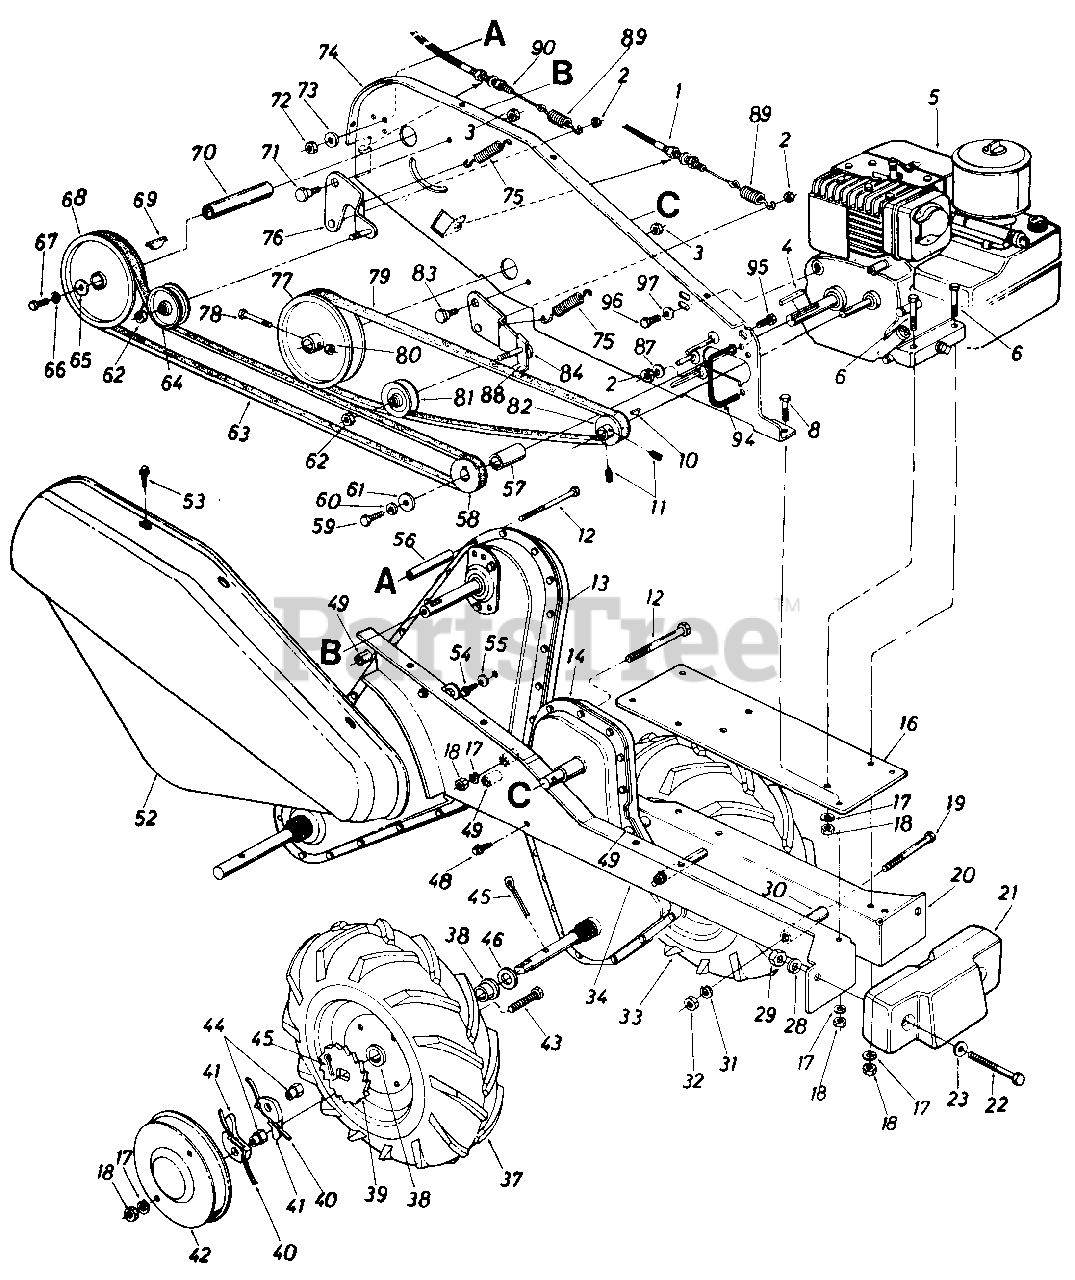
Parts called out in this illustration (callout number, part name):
1	Clutch Control Cable
2	Hex Cent. L-Nut 1/4-20 Thd.
3	Hex Cent. L-Nut 3/8-16 Thd.*
4	Sq. Key 3/16" Dia. x .75
5	Engine
6	Hex Bolt 5/16-18 x 1.50" Lg.*
8	Hex Bolt 5/16-18 x .75" Lg.*
10	Hi-Pro Key #5 Woodruff
11	Set Scr. 1/4-28 x .25" Lg.
12	Hex Bolt 5/16-18 x 3.0" Lg.*
18	Hex Nut 5/16-18 Thd.*
19	Hex Bolt 3/8-24 x 3.0" Lg.*
22	Hex Bolt 1/2-13 x 4.0" Lg.
23	Fl-Wash. 1/2" I.D. x 1.0" O.D.
28	L-Wash. 1/2" I.D.*
29	Hex Nut 1/2-13 Thd.*
30	Spacer 3/8" I.D. x 5/8" O.D. x 2.18" Lg.
31	L-Wash. 3/8" I.D.*
32	Hex Nut 3/8-24 Thd.*
33	Comp. Wheel Ass'y.-L.H.
38	Flange Brg. 7/8" I.D. x 1.12" Lg.
39	Ratchet Wheel
40	Nylon Spring
41	Pawl.44" I.D.
42	Wheel Cover
43	Hex Bolt 5/16-18 x 1.25" Lg.*
44	Special Hex-Nut 5/16-24 Thd.
45	Cotter Pin 1/8" Dia. x 1.25"*
46	Fl-Wash. 7/8" I.D. x 1-3/8" O.D. x .06
48	Hex Wash. Self-Tap Scr. 5/16-24 x .50" Lg.
49	Spacer 5/16" I.D. x .96" Lg.
52	Belt Cover
53	Hex Wash. S-Tap Scr. 1/4-20 0 x.50" Lg.
54	Hex Wash. S-Tap Scr. 1/4-20 0 x 3/8" Lg.
55	Bell-Wash. 1/4" I.D.
56	Spacer 3/8" I.D. x 2.0" Lg.
57	Spacer 3/4" I.D. x 1.56" Lg.
58	1/2" "V"-4L Pulley 3/4" I.D. x 2.59" O.D.
59	Hex Bolt 3/8-24 x 1.00" Lg.
60	L-Wash. 3/8" I.D.*
61	FL-Wash. 3/8" I.D. x 1.25" O.D.
62	Hex L-Nut 3/8-24 Thd.
63	"V"-Belt
64	Fl-Idler Pulley 3.75" O.D. x 3/8" I.D.
65	Fl-Wash. .25" I.D. x .93" O.D. x .120
66	L-Wash. 1/4" I.D.
67	Hex Bolt 1/4-28 x .75" Lg.
68	Split Pulley 6" Dia. x 5/8"-I.D.
69	Hi-Pro Key
71	Shld. Bolt 1/2" Dia. x .210"
72	Hex Nut 5/16-18 Thd.
73	L-Wash. 5/16" I.D.
74	Side Plate Ass'y.
75	Ext. Spring 50" O.D. x 1.55"
76	Idler Bracket Ass'y.-Tines
77	Pulley 6" Dia. x 5/8" I.D.
78	Hex Bolt 1/4-28 x 1.50" Lg.
80	Hex Cent. L-Nut 1/4-28 Thd.
81	"V"-ldler Pulley 2-5/8" O.D.
82	1/2" "V"-Pulley 2 1/4" O.D. x .50" I.D.
83	Shld. Bolt 1/2" Dia. x .160"
84	Idler Bracket Ass'y.-Wheels
87	Bell-Wash. 1/4" I.D.
88	Belt Keeper Ass'y.
90	Clutch Control Cable
94	Belt Keeper
95	Hex Bolt 1/4-20 x 1.25" Lg.
96	Hex Bolt 5/16-24 x .62" Lg.
97	Bell-Wash. 5/16" I.D.
